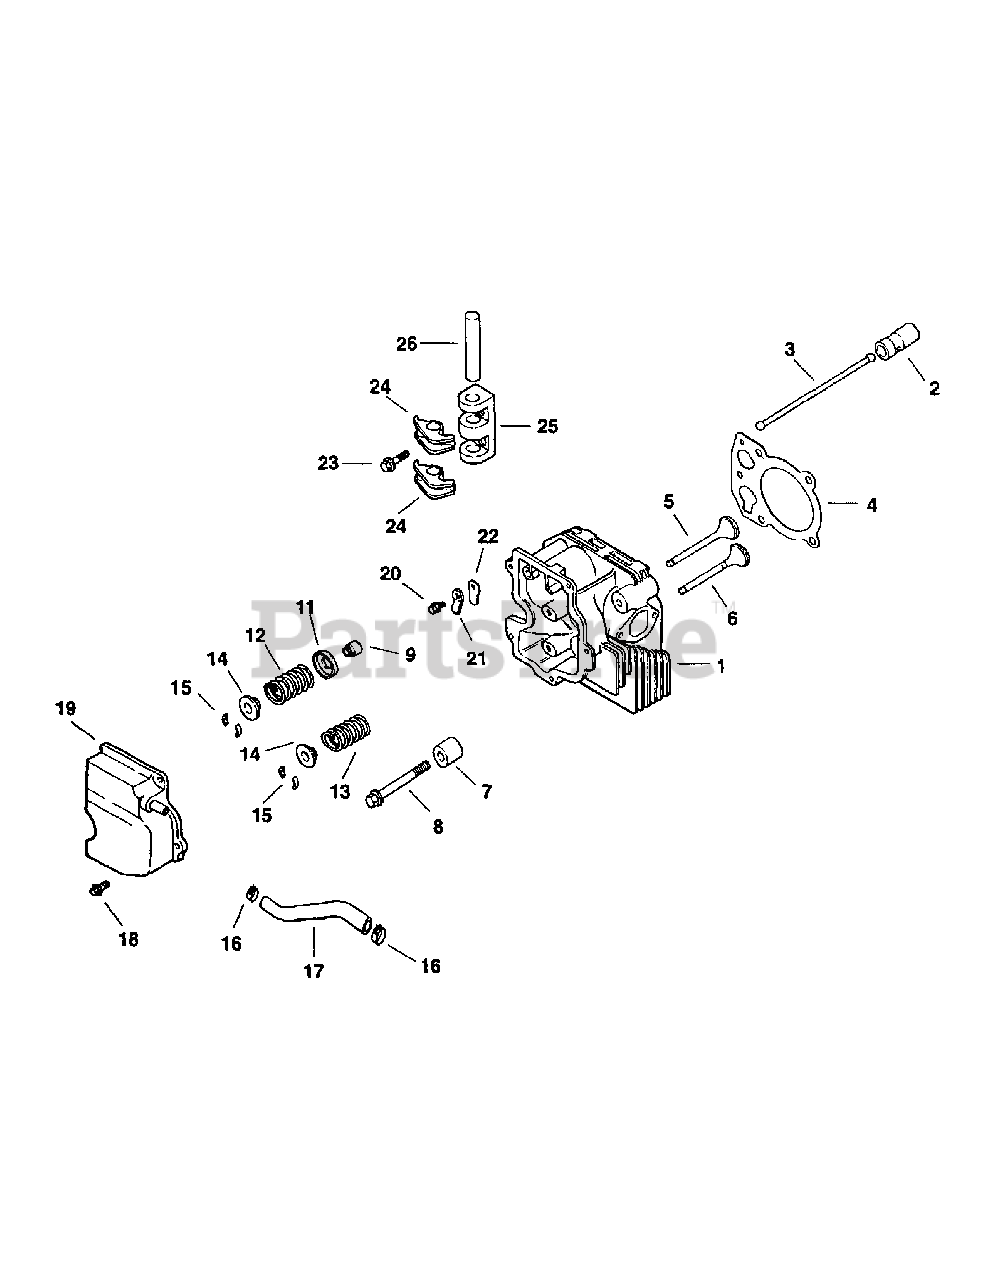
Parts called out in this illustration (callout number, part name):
1	Head, Cylinder
2	Lifter, Valve
3	Rod, Push
4	Gasket, Cylinder Head
5	Valve, Intake (Std.)
5	Valve, intake (.25 o.s.)
6	Valve, Exhaust (Std.)
6	Valve, Exhaust (.25 o.s.)
7	Spacer, Head Bolt Exhaust Port
8	Screw, Hex Flange
9	Seal, Valve Stem
11	Spring, Retainer
12	Spring, Intake Valve
13	Spring, Exhaust Valve
14	Cap, Valve Spring
15	Retainer Kit
16	Clamp, Hose
17	Hose, Breather
18	Screw, Hex Flange
19	Cover, Valve w/Nipple
20	Screw, Hex Flange
21	Retainer, Breather Reed
22	Reed, Breather
23	Screw, Hex Flange
24	Arm, Rocker
25	Bridge, Rocker Arm
26	Shaft, Rocker Arm
